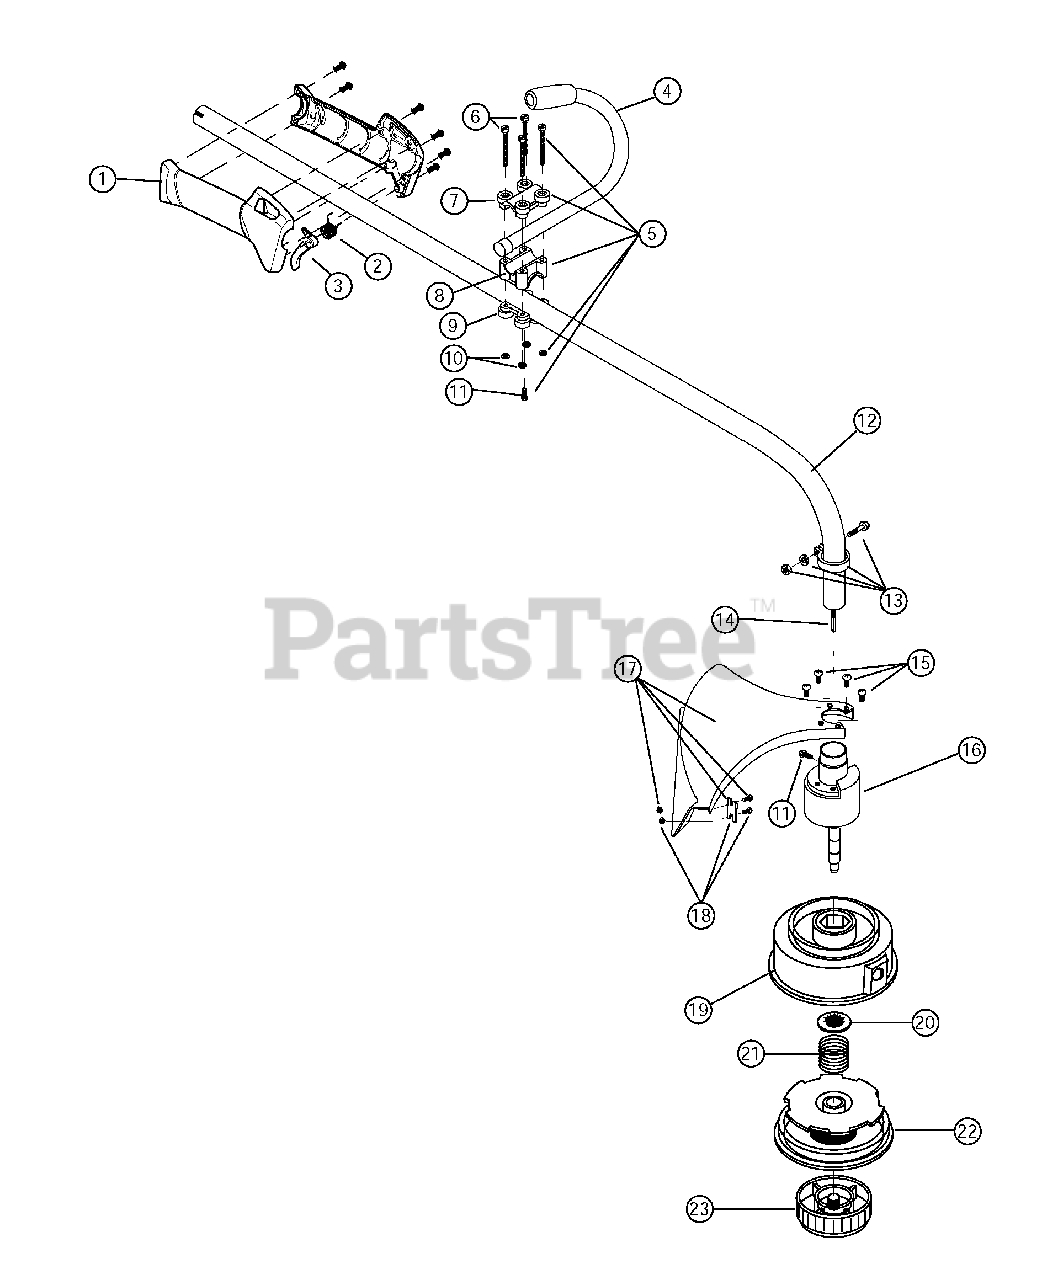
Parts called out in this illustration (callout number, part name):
1	Throttle Housing and Trigger Assembly
2	Throttle Trigger Spring
3	Throttle Trigger
4	J-Handle Assembly
5	Handle Bracket Assembly
7	Upper Handle Clamp
8	Middle Handle Clamp
9	Lower Handle Clamp
11	Anti-Rotation Screw
12	Drive Shaft Housing Assembly
13	Lower Clamp Assembly
14	Flexible Drive Shaft
15	Shield Mounting Screw
16	Bushing Housing Assembly w/Spool Shaft
17	Shield and Blade Assembly
18	Blade Assembly
19	Outer Spool and Eyelet Assembly
20	Retainer
21	Spring
22	Inner Reel
23	Bump Head Knob Assembly
